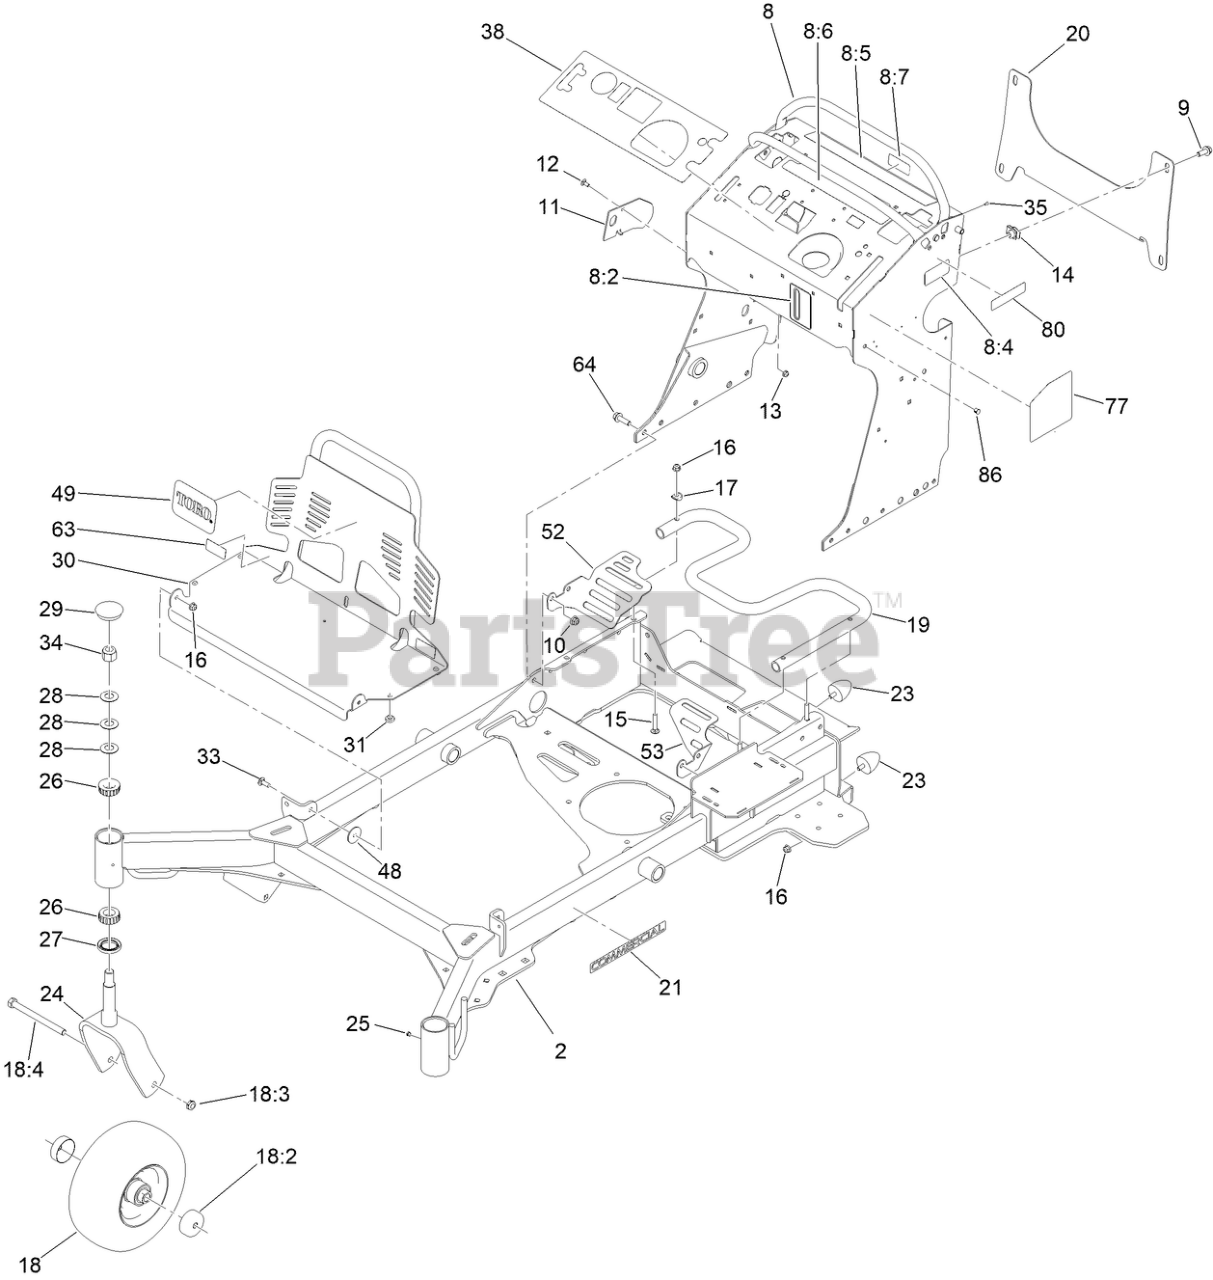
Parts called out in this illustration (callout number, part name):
8	TOWER DECAL ASM
8:2	DECAL-LEVEL, OIL
8:4	DECAL-FILL, FUEL
8:5	DECAL-WARNING
8:6	DECAL-CONTROLS
8:7	DECAL-FUSE
9	SCREW-HHF
10	NUT-HF, NI
11	PLATE-STRIKER
12	SCREW-CARR
13	NUT-HF
14	NUT-TINNERMAN
15	BOLT-CAR
16	NUT-HF, NI
17	WASHER
18	MF WHEEL TIRE BEARING ASM
18:2	GUARD-SEAL
18:3	NUT-HEX
18:4	SCREW-HH
19	TUBE-MOUNT, FUEL TANK
20	BRACKET-CROSS
21	DECAL-COMMERCIAL
23	BUMPER-RUBBER
24	CASTER FORK ASM [RED]
26	BEARING-ROLLER, TAPERED
27	SEAL-GREASE
28	WASHER-BELLVILLE
29	CAP-GREASE
30	GUARD-ENGINE
31	BUMPER
33	BOLT-CARR
34	NUT-LOCK, NI
35	RIVET-POP
38	DECAL-PANEL, CONTROL
48	WASHER-NYLON
52	GUARD-FAN, RH
53	GUARD-FAN, LH
63	DECAL-WARNING, NO RIDERS
64	SCREW-HHF
77	DECAL-SERVICE AID
80	DECAL-ARRESTOR, SPARK
86	DOME PANEL PLUG
